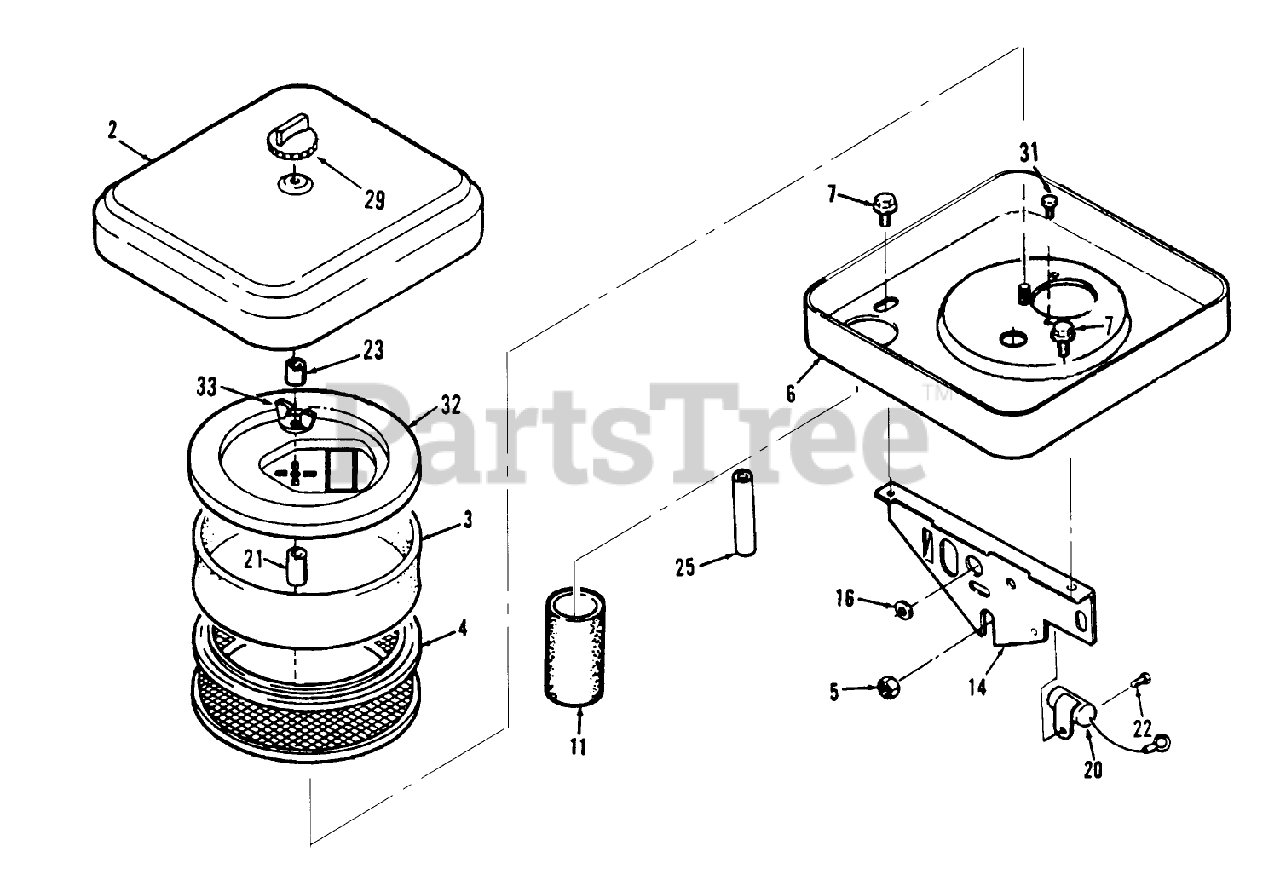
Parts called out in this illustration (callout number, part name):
3	AIR CLEANER ELEMENT
7	SCREW-TAPPING
14	SUPPORT-AIR CLEANER
16	GROMMET
20	CONDENSER
32	ELEMENT COVER KIT
